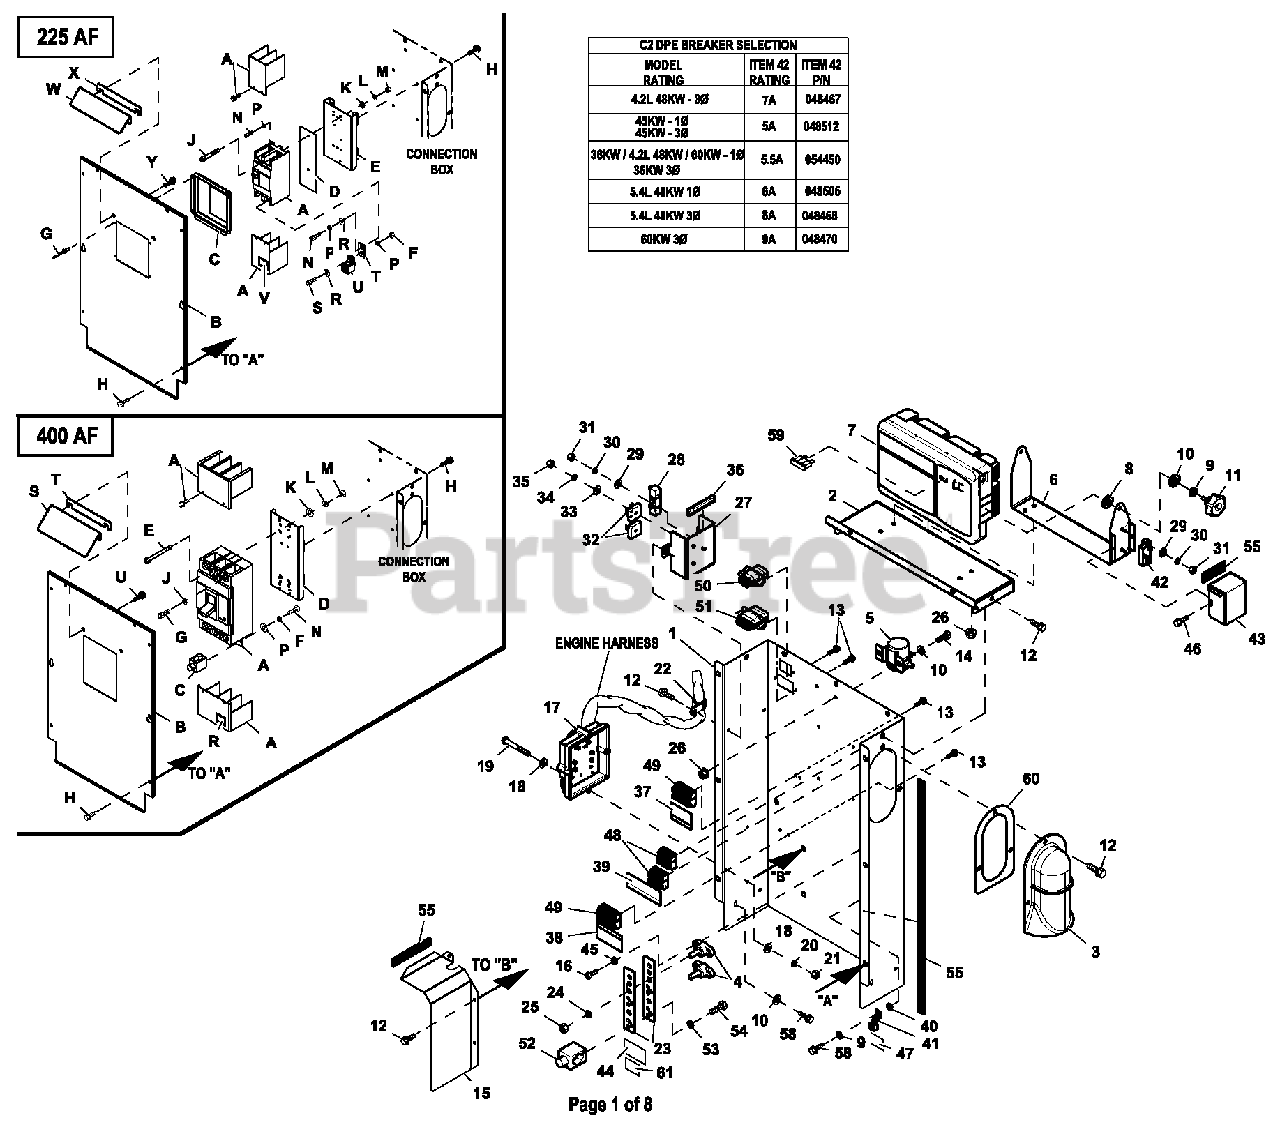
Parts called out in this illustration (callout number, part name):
1	ROTOR-2390-45KD1 CPL
2	ROTOR-2390-35KD1 CPL
3	ROTOR-2390-45KD1 CPL (G2)
4	ROTOR-2390-35KD1 CPL (G2)
5	ROTOR 25KW 3PH DIRECT 390 1800
6	ROTOR 25KW 1PH DIRECT 390 1800
7	ASSY CTRL PROGRAMMED
8	WASHER FLAT NYLON 0.257 X 0.625
9	WASHER LOCK M6-1/4
10	STATOR-390 45K 2P 1PH DIRECT
11	STATOR-2390-35AD1 CPL
12	STATOR-2390-35KD1 CPL
13	STATOR-2390-35GD1 CPL
14	STATOR-2309-45KW 2P 3PH 208V
15	STATOR-2309-45-KD1 CPL
16	SCREW PHTT M4-0.7 X 12 ZP
17	ASSY PROG 2010 IGN MOD 6 CYL
18	WASHER FLAT #10 ZINC
19	SCREW PPHM #10-32X2
20	WASHER LOCK #10
21	NUT HEX #10-32 STEEL
22	CLAMP STL/VNL 1.06 X .406 Z
23	NEUTRALBLOCK390/200 400A
24	WASHER LOCK 3/8
25	NUT HEX 3/8-16 STEEL
26	NUT FLANGE M6-1.0 NYLOK
27	COVER VOLTAGE SHIELD
28	RES WW 15R 5% 25W QK CONN
29	WASHER FLAT M3
30	WASHER LOCK M3
31	NUT HEX M3-0.5 G8 CLEAR ZINC
32	DIODE BRIDGE 1P 35A 1000V
33	WASHER FLAT M5
34	WASHER LOCK M5
35	NUT HEX M5-0.8 G8 CLEAR ZINC
36	TRIM VINYL BLACK 1/8GP (3"LG)
37	DECAL CUSTOMER POWER CONNECT
38	DECALCUSTOMERCONTROLCONNECT
39	DECAL CONBOX TB1 CONNECTIONS
40	WASHER LOCK EXT 1/4 STL
41	LUG SLDLSS #2-#8 X 17/64 CU
42	CIRCUIT BREAKER
43	COVER DPE BREAKER NEXUS RAW
44	DECAL NEUTRAL
45	WASHER LOCK#8-M4
46	SCREW HHTT M4-0.7 X 8 ZP
47	DECAL GROUND LUG
48	TERM BLOCK 3P UL 12-20AWG
49	TERM BLOCK 4P UL 12-20AWG
50	MX150L SLRRMNT 22-18 8P W/O GA
51	MX150L SLRRMNT 22- 18 12P W/OGA
52	LUG SLDLSS 600/250-1/0X1/4-28
53	WASHER LOCK 1/4- M6 SS
54	SCREW HHC 1/4-28 X 3/4 G5
55	TAPE ELEC 1/2 FOAM (69"LG)
57	HARNCONBOXNEXUS(NOTSHOWN)
58	SCREW HHTT M6-1.0 X 16 ZYC
59	FUSE ATO TYPE 7.5AMP (BROWN)
60	GASKEToWIREoENTRYoCOVERo
61	DECAL CAUTION ELEC SHOCK SM
A	CB 175A 2 POLE 240V 225AF
B	COVER CB C2 CPL
C	COVER CB DISH 2P G 225AF
D	INSULATOR CB 2P 225AF
E	STANDOFF CB BOX CONBOX
F	NUT HEX M8-1.25 G8 CLEAR ZINC
G	RIVET POP .125 X .275 SS
H	SCREW HWHT M6-1 X 16 N WA Z/JS
J	SCREW RHM #8-32X3-1/4
K	WASHER FLAT #8 ZINC
L	WASHER LOCK#8-M4
M	NUT HEX #8-32 STEEL
N	SCREW SHC M8-1.25 X 20 G8
P	WASHER LOCK M8-5/16
R	WASHER FLAT 5/16-M8 ZINC
S	SCREW SHC M8-1.25 X 25 C12.9
T	BUS BAR 200A LUG ADAPTOR
U	LUG SLDLSS 300 MCM-6 AL/CU
V	DECAL TERMINAL SHOCK HZD BI
W	SHIELD-SM CIRCUIT BREAKER
X	GASKET-CB SHIELD C2
Y	SCREW HWHTF M6-1.0X16
A	CB 0250A 3P 480V G 400AF
B	COVER CB 400AF C2 CONBOX
C	LUG SLDLSS 600/250-1/0X1/4-28
D	STANDOFF CB MOUNT CONBOX
E	SCREW RHM 10-32X4
F	WASHER LOCK M6-1/4
G	SCREW SHC M10-1.5 X 25 C12.9
J	WASHER LOCKM10
K	WASHER FLAT #10 ZINC
L	WASHER LOCK #10
M	NUT HEX #10-32 STEEL
N	SCREW HHC 1/4-28 X 1/2 G5
P	WASHER FLAT 1/4-M6 ZINC
R	DECAL TERMINAL SHOCK HZD BI
S	SHIELD-LGE CIRCUIT BREAKER
T	GASKET-CB SHIELD C2
U	SCREW HWHTF M6-1.0X16
